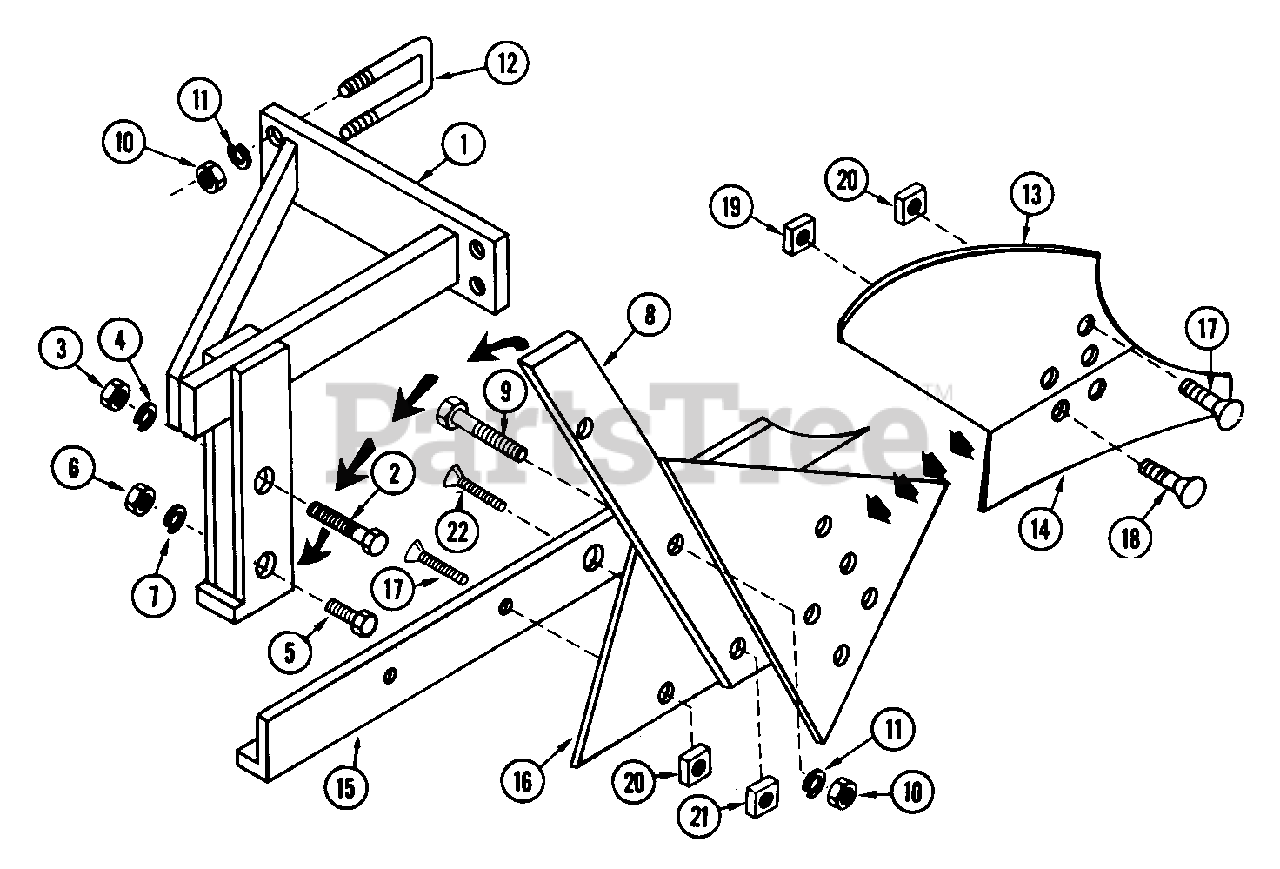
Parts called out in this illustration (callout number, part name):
1	MOLD BOARD MAIN FRAME
2	BLT-HEX .31-18X2.50 PL GR2
3	NUT-HEX .312-18
4	WSHR-LK .312X.097 PL HVY
5	BLT-HEX .62-18X2.50 GR2
6	NUT-HEX .625-11
7	WSHR-LK .625X.156 MED PL
8	MOLD BOARD EXTENSION LEG
9	BLT-HEX .50-13X2.00 GR2
10	NUT .50-13 PL
11	WSHR-LK .500X.151 HVY PL
13	MOLD BOARD BOTTOM
17	BLT-PLOW .38-16X1.0
18	BLT-PLOW .44-14X.75
19	NUT-SQ .437-14
20	NUT-SQ .375-16 PL
21	NUT-SQ .50-13
22	BLT-PLOW .50-13X2.0
